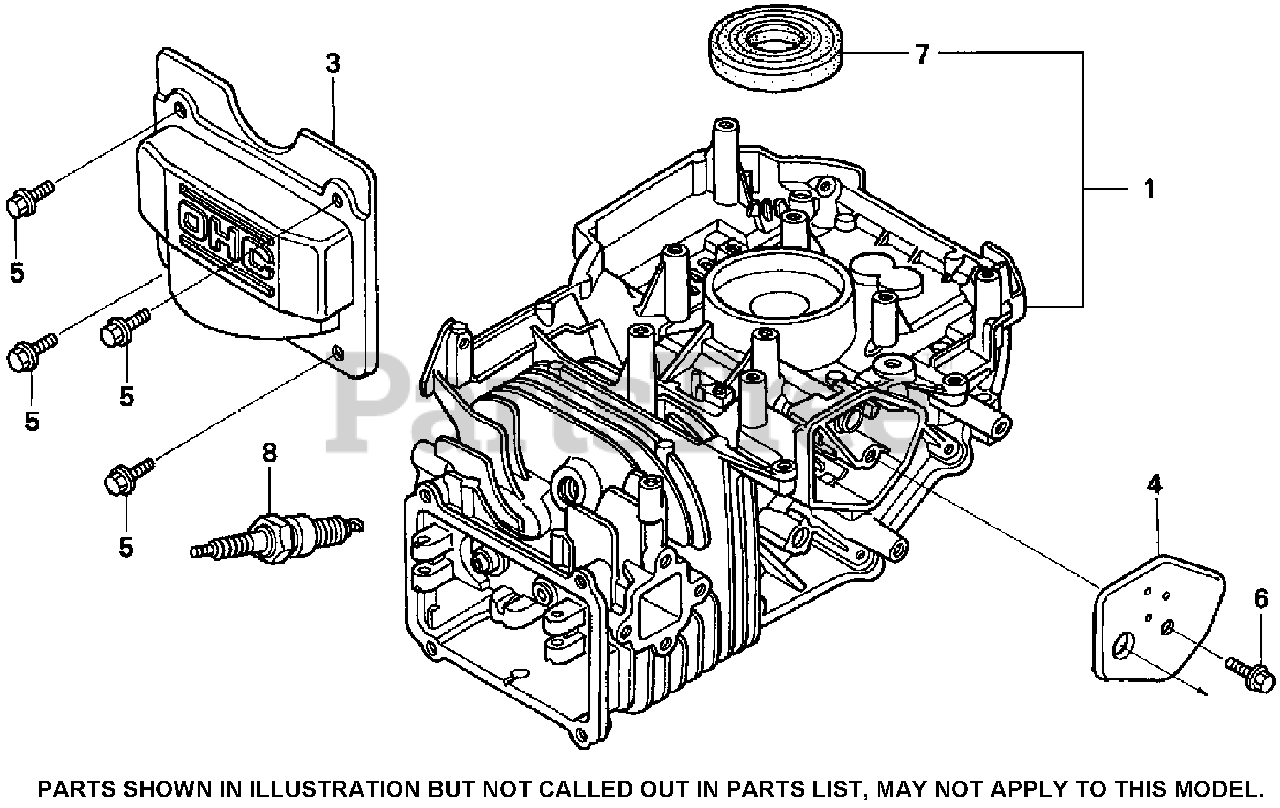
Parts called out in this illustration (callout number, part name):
1	CYLINDER ASM (010)
3	COVER-HEAD
4	COVER-BREATHER (BREATHER VALVE ASM)
5	BOLT-FLANGE (6X12) (CT200)
6	BOLT-FLANGE (6X14)
7	SEAL (25.4X62X6)
8	SPARK PLUG (BPR6ES) (NGK)
